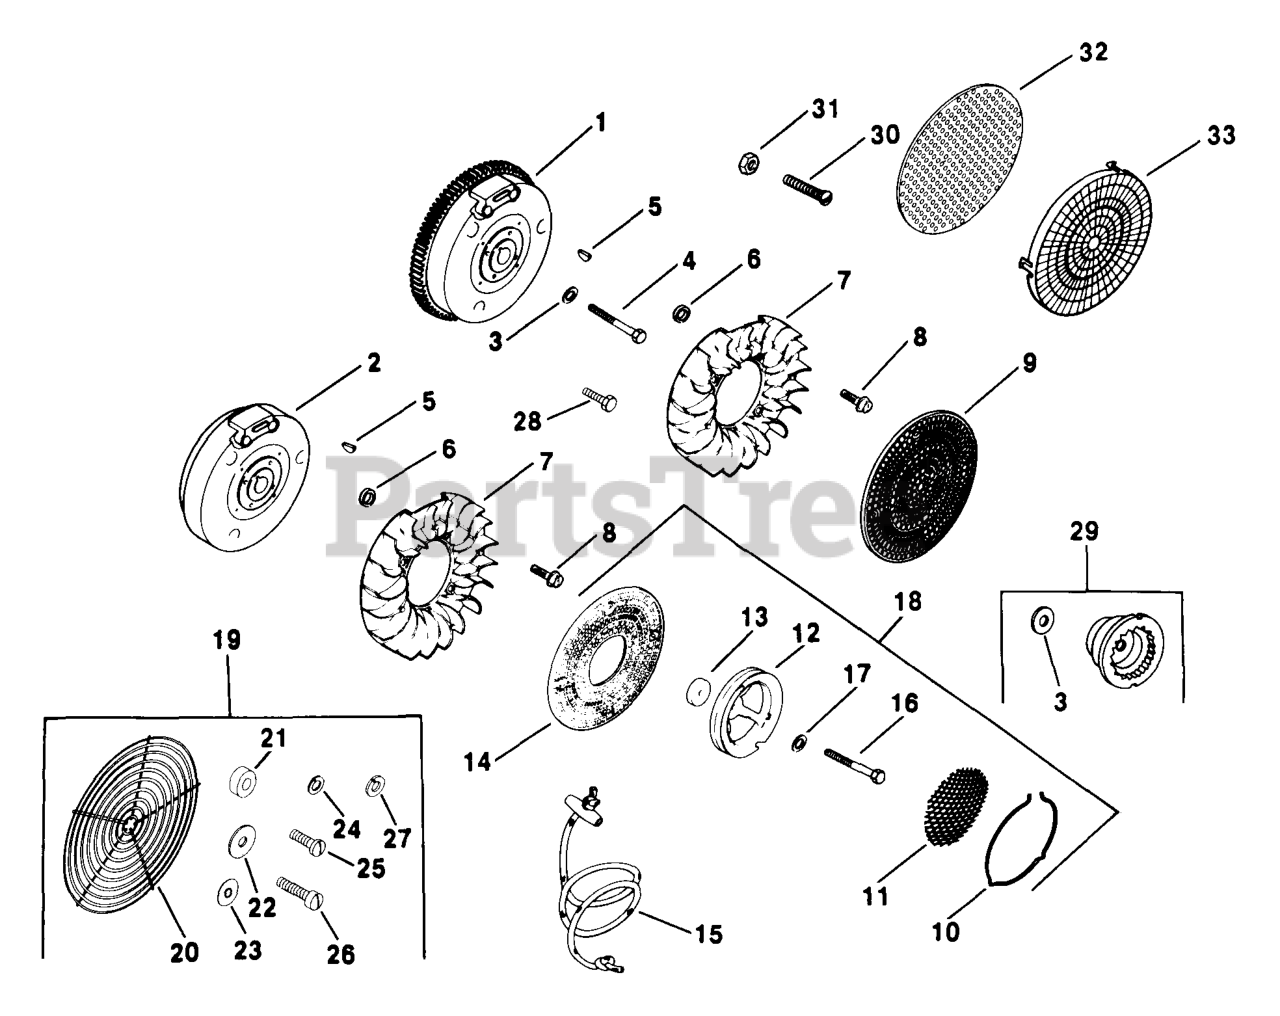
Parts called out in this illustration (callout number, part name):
1	FLYWHEEL - DISCONTINUED
3	WASHER - USE 52 468 15
4	SCREW - USE 25 086 24
5	KEY, 3/16" X 1"
8	SCREW, WSH HD 1/4-20X5/8" - DISCONTINUED
9	SCREEN, GRASS
